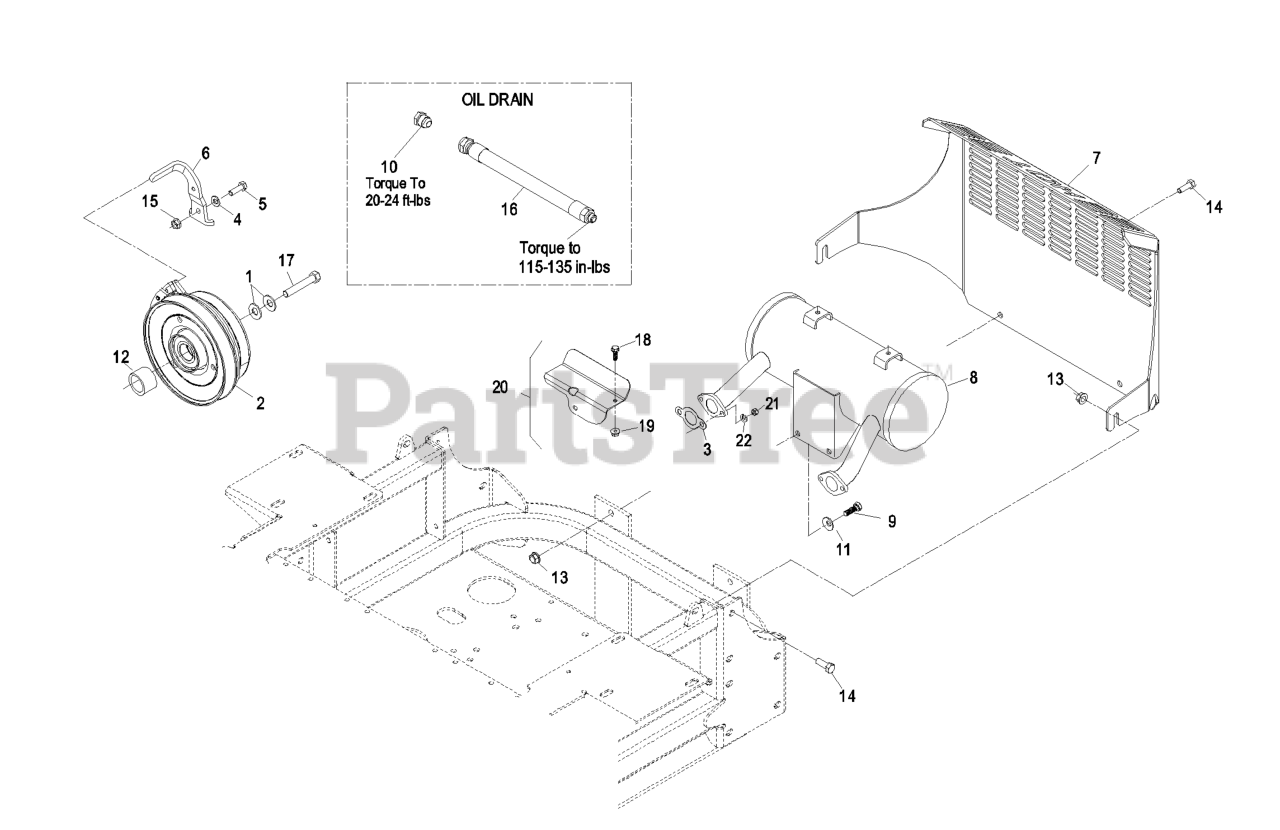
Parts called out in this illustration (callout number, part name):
1	WASHER-SPRING
2	KIT,SPOT BRAKE CLUTCH 1.1
4	WASHER-SPRING
5	SCREW-HH
6	ANCHOR-CLUTCH
7	GUARD, REAR KC
8	KIT,MUFFLER KOHLER
9	SCREW-HH
11	SCREW-HH
12	SPACER-CLUTCH
13	NUT-HHF, WHIZ
14	SCREW-HH
17	SCREW-HH
18	SCREW-HH
20	CABLE HEAT SHIELD KIT
21	NUT-HEX
22	WASHER-LOCK
